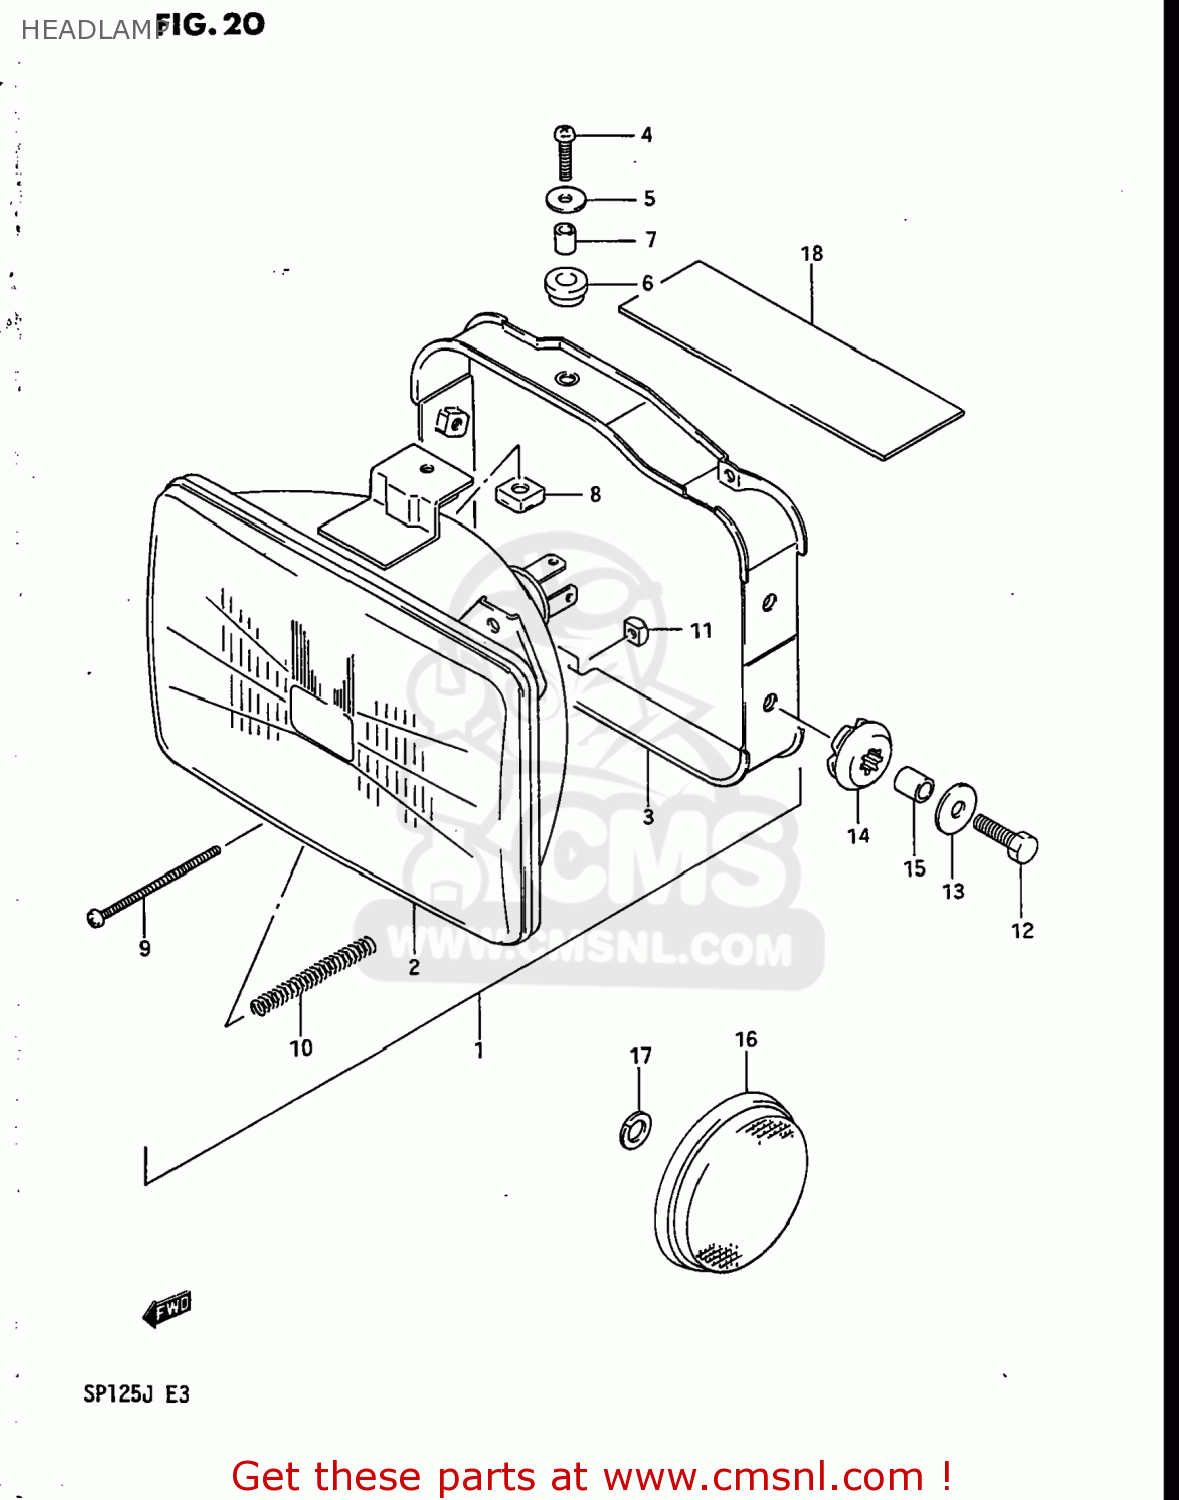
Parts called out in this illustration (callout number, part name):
1	HEADLAMP ASSEMBLY
2	LAMP UNIT,SHIELD BEAM
3	HOUSING
4	SCREW 5X20
5	WASHER
6	CUSHION
7	SPACER
8	NUT
9	SCREW,HEADLAMP ADJUST
10	SPRING
11	NUT
12	BOLT
13	WASHER (6.5X20X1.2)
14	CUSHION
15	SPACER (6.1X9X9)
16	REFLEX REFLECTOR,FR
17	LOCK WASHER
18	CUSHION
